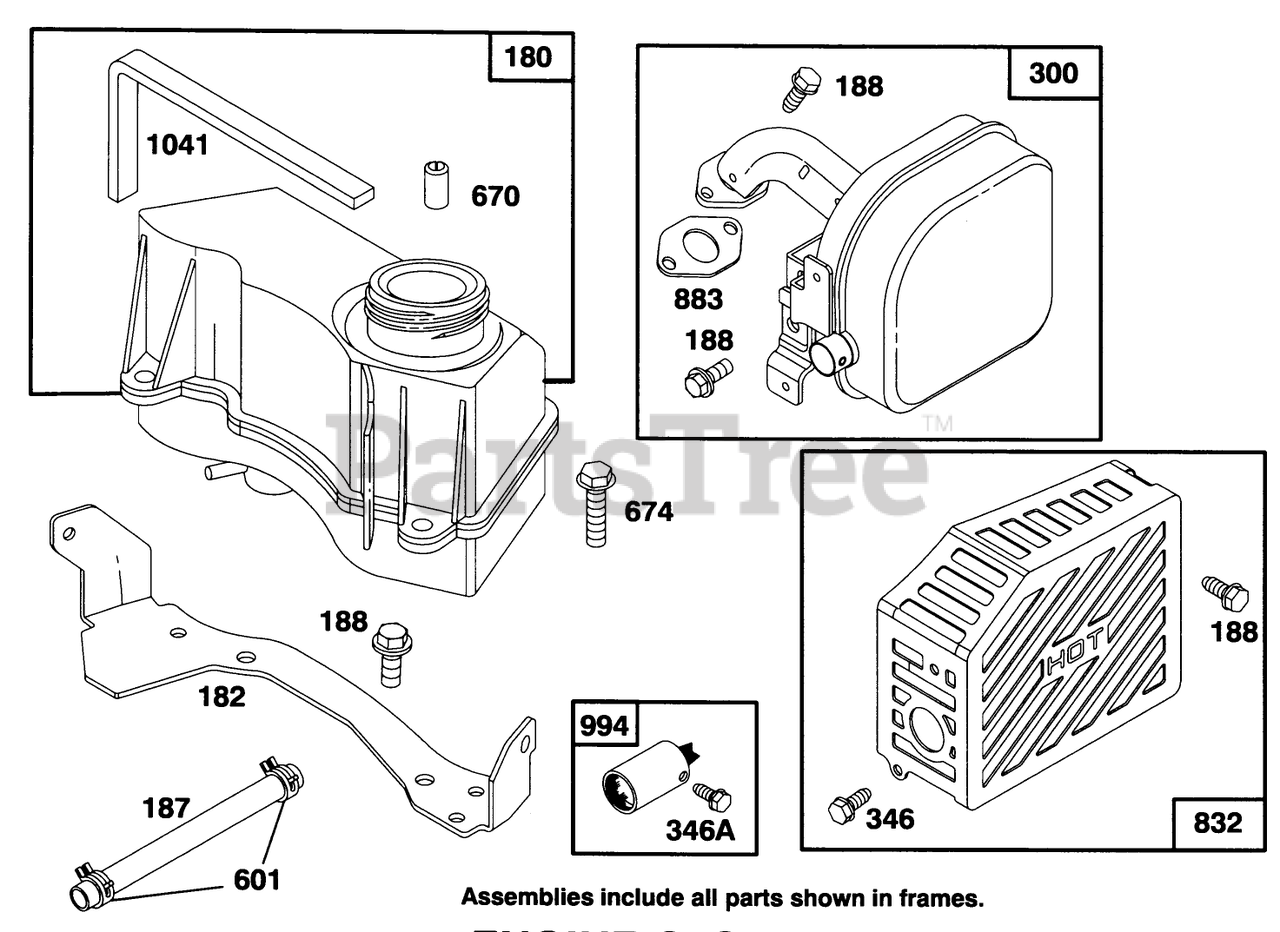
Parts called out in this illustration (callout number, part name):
180	TANK ASSY - FUEL
188	SCREW - SEM
300	MUFFLER - EXHAUST
346	Screw-Hex
601	CLAMP - CL PIPE
670	SPACER
674	SCREW - HEX HEAD
